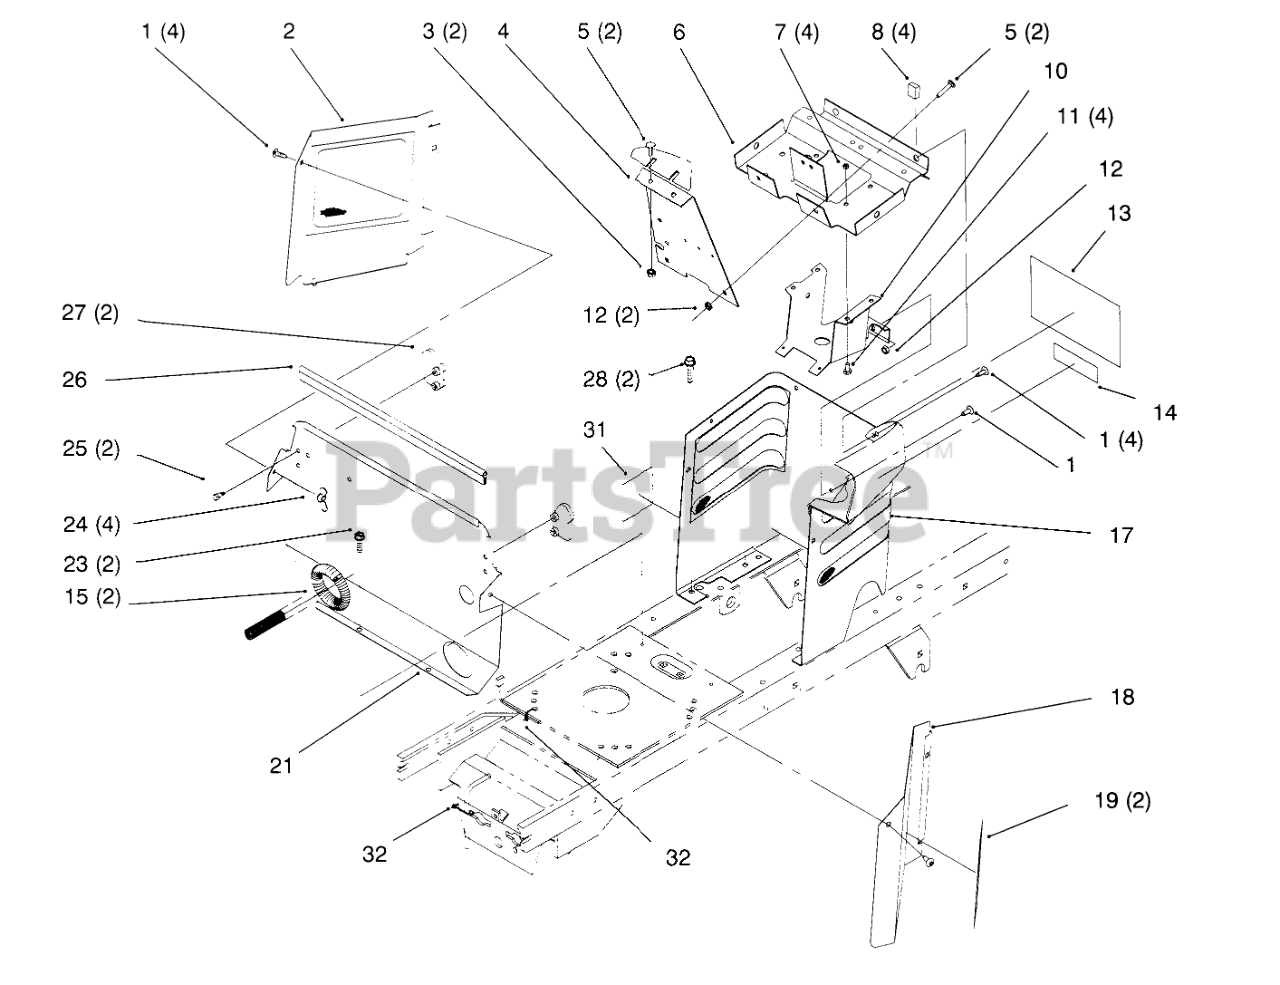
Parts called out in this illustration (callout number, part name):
1	SCREW-HH
2	RH SIDE COVER ASM
3	NUT-KEPS
4	PANEL-SUPPORT DASH (BLACK)
5	SCREW-CARR
6	SUPPORT-DASH
7	NUT-HEX
8	NUT RETAINER - J TYPE
10	BRACKET-COLUMN, LOWER
11	SCREW-HH
12	NUT-LOCK, NI
13	DECAL-DANGER
14	DECAL-INSTRUCTION
15	COVER-SHAFT, DRIVE
17	HOODSTAND W/DECALS BLK
18	LH COVER ASM
19	DECAL - 266-H
21	FIREWALL (BLACK)
23	SCREW-HWH
24	NUT-WING
25	SCREW-PLASTITE
26	TRIM-SEAL, FIREWALL
27	LATCH-HOOD
28	SCREW-HWHTF
32	TIE-CABLE
